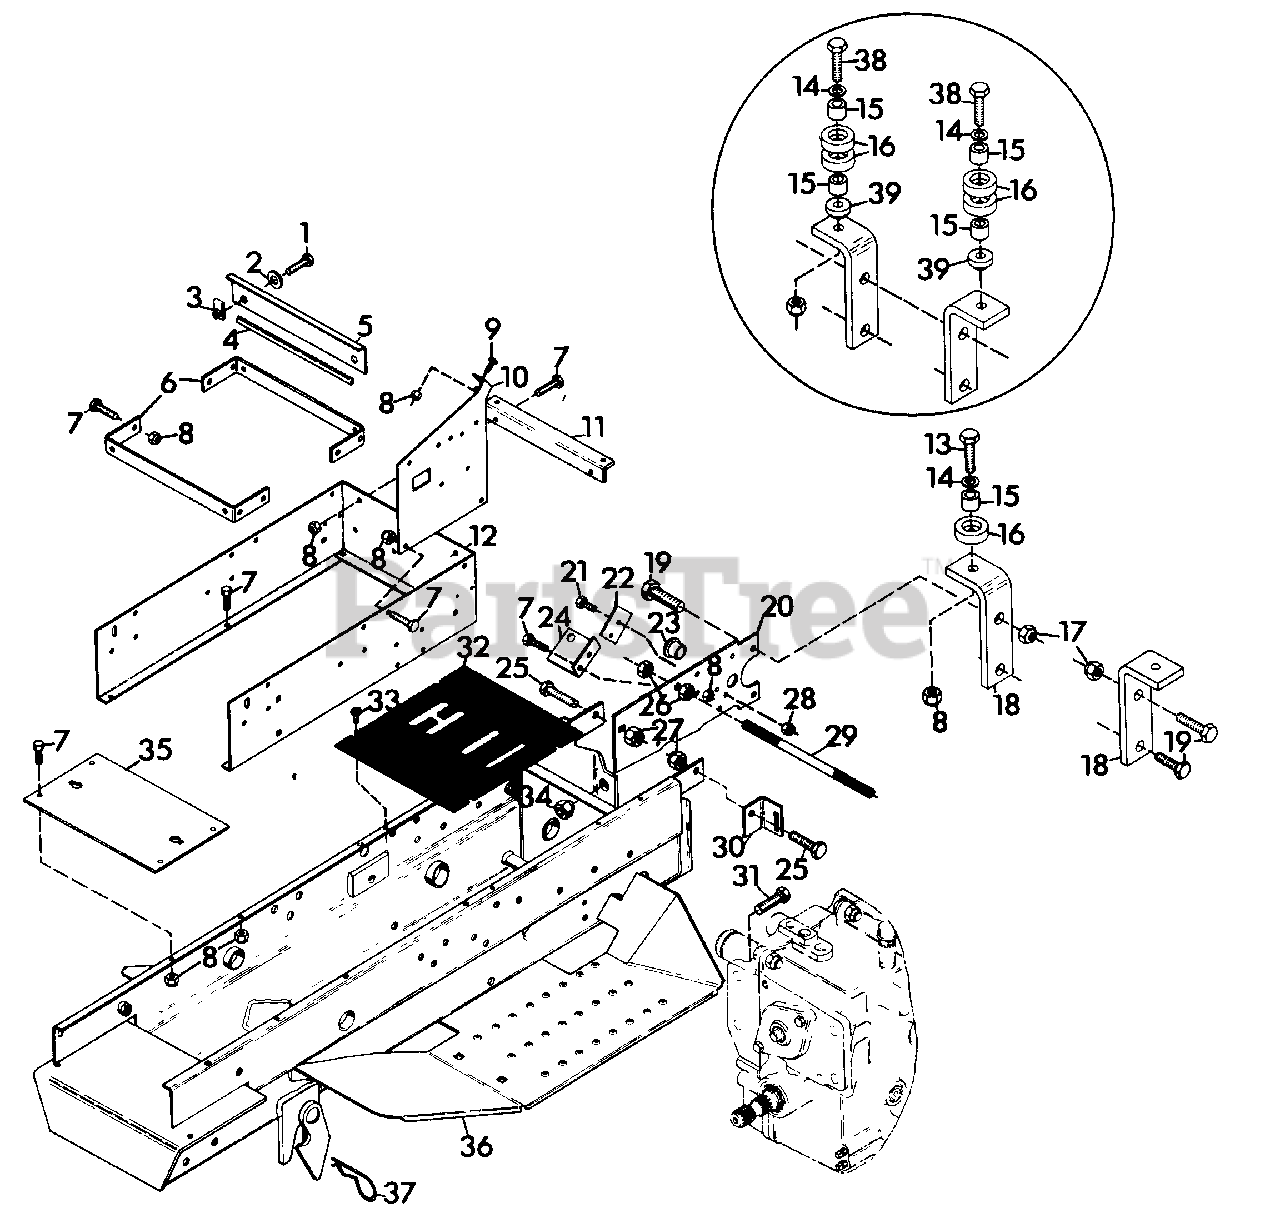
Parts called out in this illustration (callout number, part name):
1	BOLT, HEX 1/4-20X.875
2	WASHER, FLAT .281X.625X.065
3	NUT, RETAINER
4	MOULDING
5	BRACKET, FORWARD TANK
6	BRACKET, FUEL TANK
7	BOLT, HEX 1/4-20X.75
8	NUT LOCK 1/4-20
9	SCREW, MACHINE 1/4-20X.75 PAN HD.
10	BRACE, INSTRUMENT PANEL L.H.
10	BRACE, INSTRUMENT PANEL R.H.
11	BRACKET, INSTRUMENT PANEL
12	SUPPORT, INSTRUMENT PANEL
13	BOLT, HEX 1/4-20X1.25
14	WASHER, FLAT .312X.734X.065
15	BUSHING, .259X.375X.25
16	BUMPER, SEAT
17	NUT, LOCK 1/2-13
18	BRACKET, REAR HITCH
19	BOLT, HEX 1/2-13X1.50
20	PLATE, FWD-REV MOUNTING
21	BOLT, HEX 5/16-18X.75
22	BRACKET, BUSHING LOCK
23	BUSHING, NYLON .76X1.00X.76 FLANGE
24	BRACKET, INTERLOCK SWITCH
25	BOLT, HEX 3/8-16X1.25
26	NUT, HEX 1/2-13
27	NUT, LOCK 3/8-16
28	NUT, LOCK 5/16-18
29	ROD, FRAME EXTENSION BRACE
30	BRACKET, FENDER HOLD-UP
31	BOLT, HEX 1/2-20X1.50
32	PLATE, MANUAL CONTROL COVER
32	PLATE, HYDRAULIC CONTROL COVER
33	SCREW, TAPPING 1/4-20X.625 PAN HD
34	NUT, RIM
35	TRAY, BATTERY
36	WELDMENT, 4-WHEEL FRAME
37	PIN, HAIR
38	BOLT, HEX 1/4-20X2.25
39	PIVOT, HOOD
